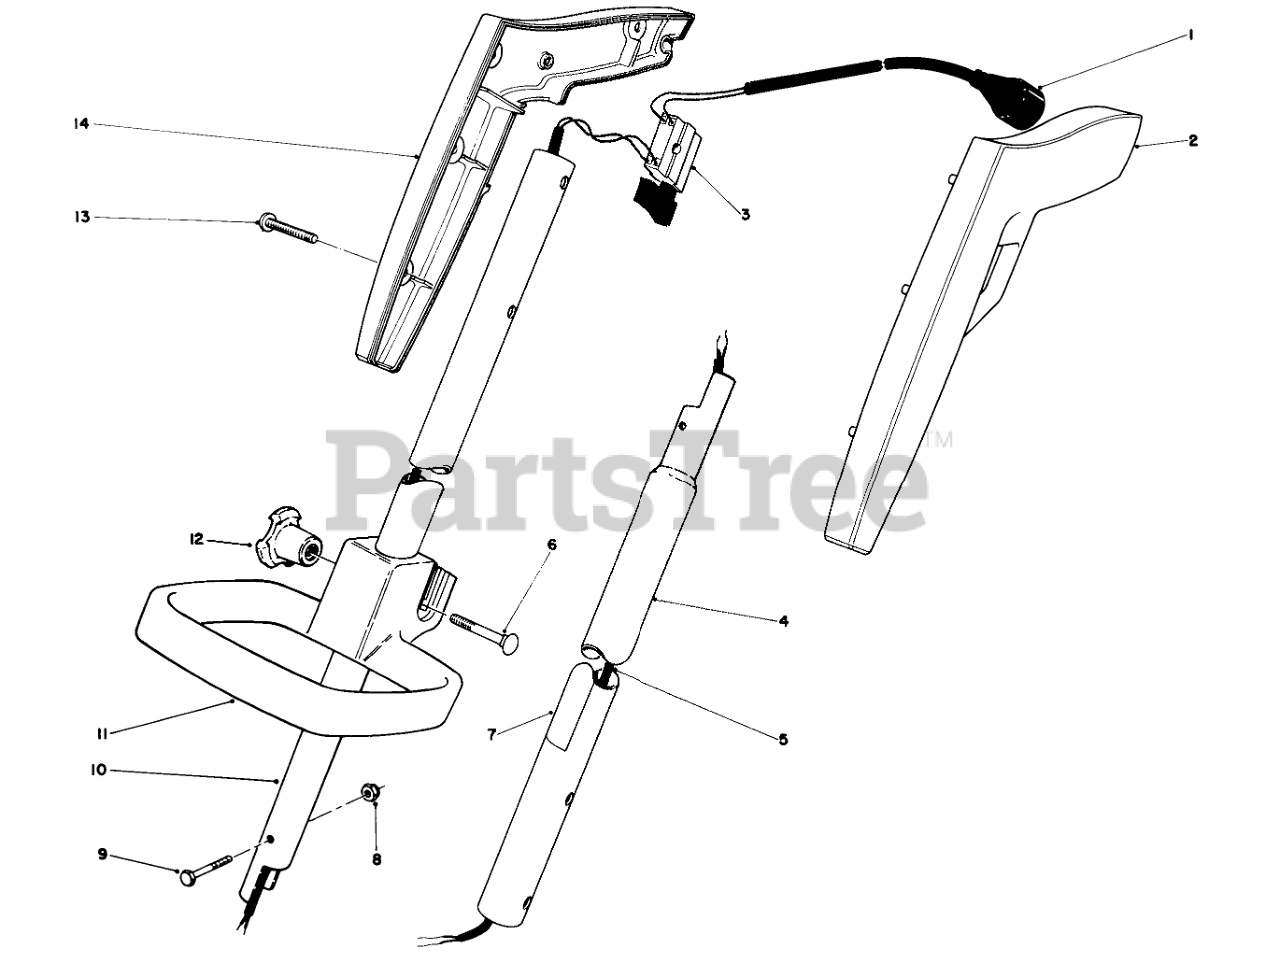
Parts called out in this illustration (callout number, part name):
1	Cord-Power
2	Grip L.H.
3	SWITCH SINGLE SPEED
4	LOWER TUBING
5	WIRE HARNESS
6	BOLT-CARR
7	REP. SERIAL PLT
8	NUT-LOCK, NI
9	HEX HD MACHINE SCREW
10	UPPER EXT TUBING
11	Handle
12	Knob
13	Screw
14	R.H. GRIP
